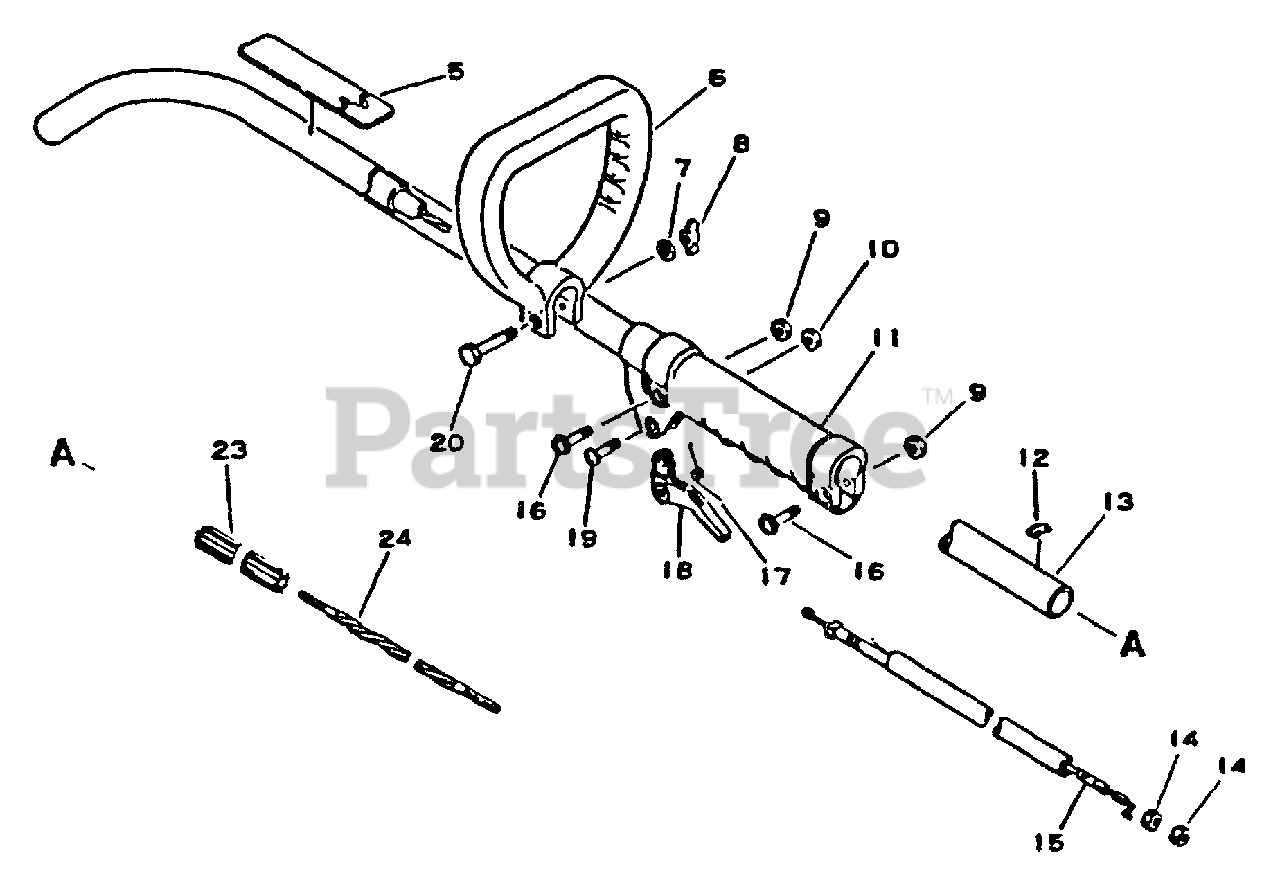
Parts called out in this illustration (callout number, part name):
5	LABEL - CAUTION
6	HANDLE - FRONT
7	WASHER 6.5×11.5×0.8
8	NUT, WING 6
9	NUT M5
10	LOCKNUT - 5
12	LABEL - ALIGNMENT
13	MAIN PIPE ASSY
15	CABLE, THROTTLE
16	SCREW 5×25
17	SPRING, THROTTLE
18	TRIGGER, THROTTLE
20	BOLT - 6×40
23	LINER - FLEXIBLE
24	DRIVESHAFT - FLEXIBLE
C5	LABEL - CAUTION
